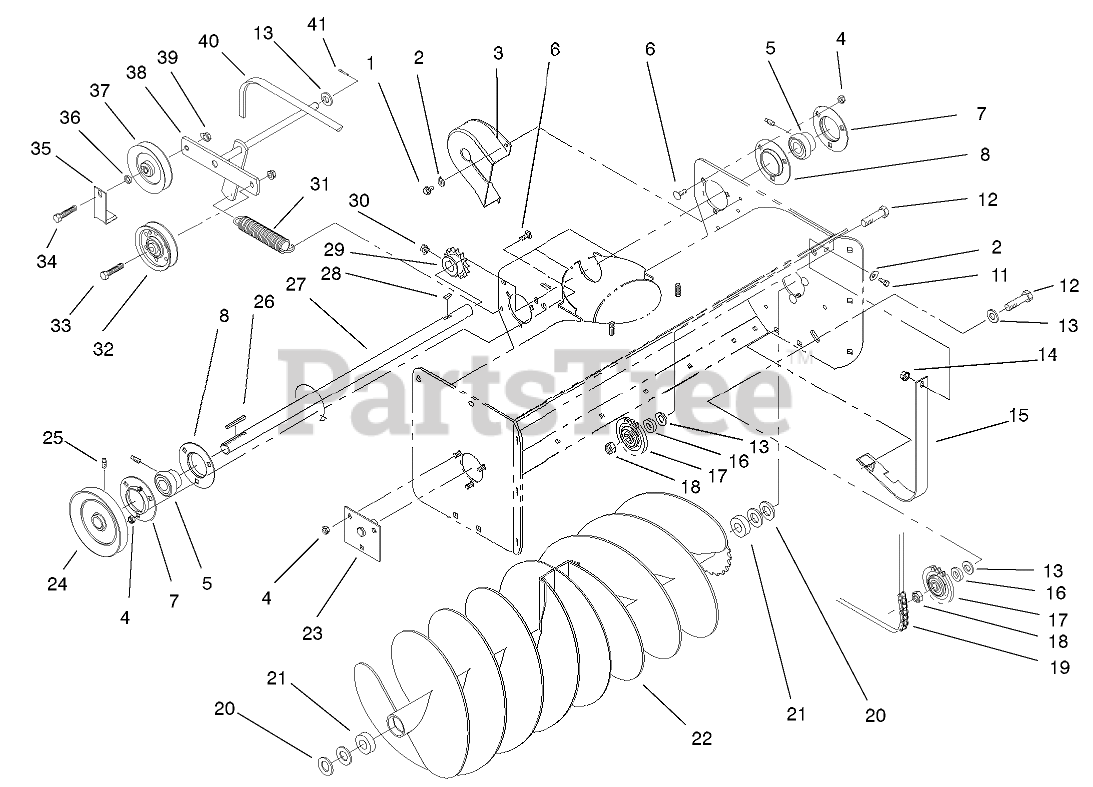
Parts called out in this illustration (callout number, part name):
1	SCREW-HWH
2	WASHER-FLAT
3	GUARD-CHAIN
4	NUT-LOCK, NI
5	BEARING AND COLLAR
6	BOLT-CARR
7	FLANGE-ZERK RELUBE
8	Flange
11	SCREW-HH
12	SCREW-HH
13	WASHER-FLAT
14	NUT-KEPS
15	GUARD-CHAIN
16	SPACER
17	SPROCKET-IDLER
18	NUT-LOCK, NI
19	CHAIN
20	WASHER-FLAT
21	BEARING-BALL
22	Auger
23	SUPPORT
24	PULLEY
25	SCREW-SQH
26	KEY-STRAIGHT
27	SHAFT-DRIVE
28	KEY-WOODRUFF
29	SPROCKET-DRIVE,14 TOOTH
30	SCREW-SET, HSH
31	SPRING-EXTENSION
32	PULLEY-IDLER, FLAT
33	SCREW-HH
34	SCREW-HH
35	BRACKET-RETAINER,BELT
36	SPACER
37	PULLEY-IDLER
38	ARM-IDLER
39	NUT-LOCK, NI
40	V-BELT
41	PIN-COTTER
